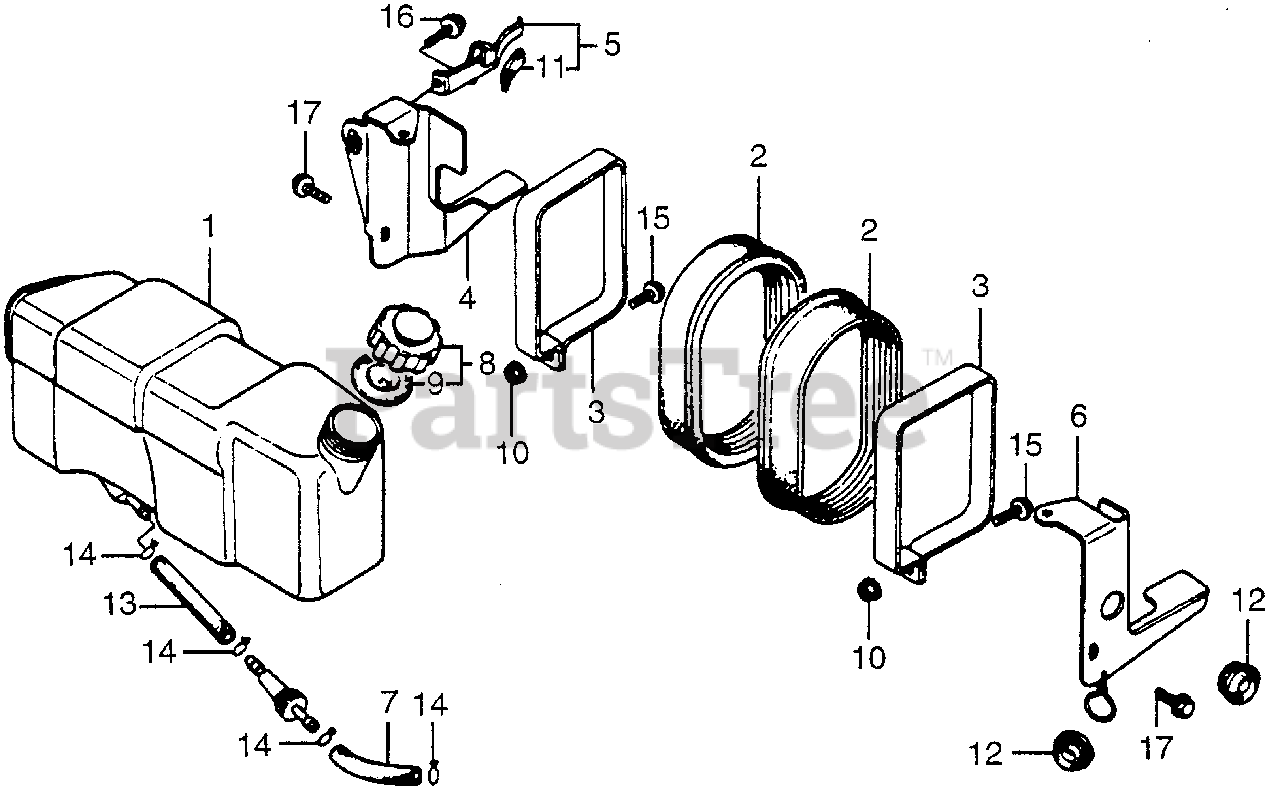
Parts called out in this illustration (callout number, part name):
1	TANK, FUEL *NH1* (BLACK)
2	RUBBER, TANK SEAT
3	BAND, FUEL TANK
4	STAY A, TANK
5	PLATE ASSY., TANK SET
6	STAY B, TANK
7	TUBE, FUEL
8	CAP ASSY., FUEL (NOT AVAILABLE)
9	GASKET, FUEL CAP
10	NUT, FLANGE (6MM)
11	RUBBER, HOOD
12	GROMMET, BREATHER PIPE (NOT AVAILABLE)
13	BULK HOSE, FUEL (5.5X8000) (5.5X55)
14	CLIP, TUBE (B10)
15	BOLT, FLANGE (6X12)
16	BOLT, FLANGE (6X14)
17	BOLT, FLANGE (6X18)
